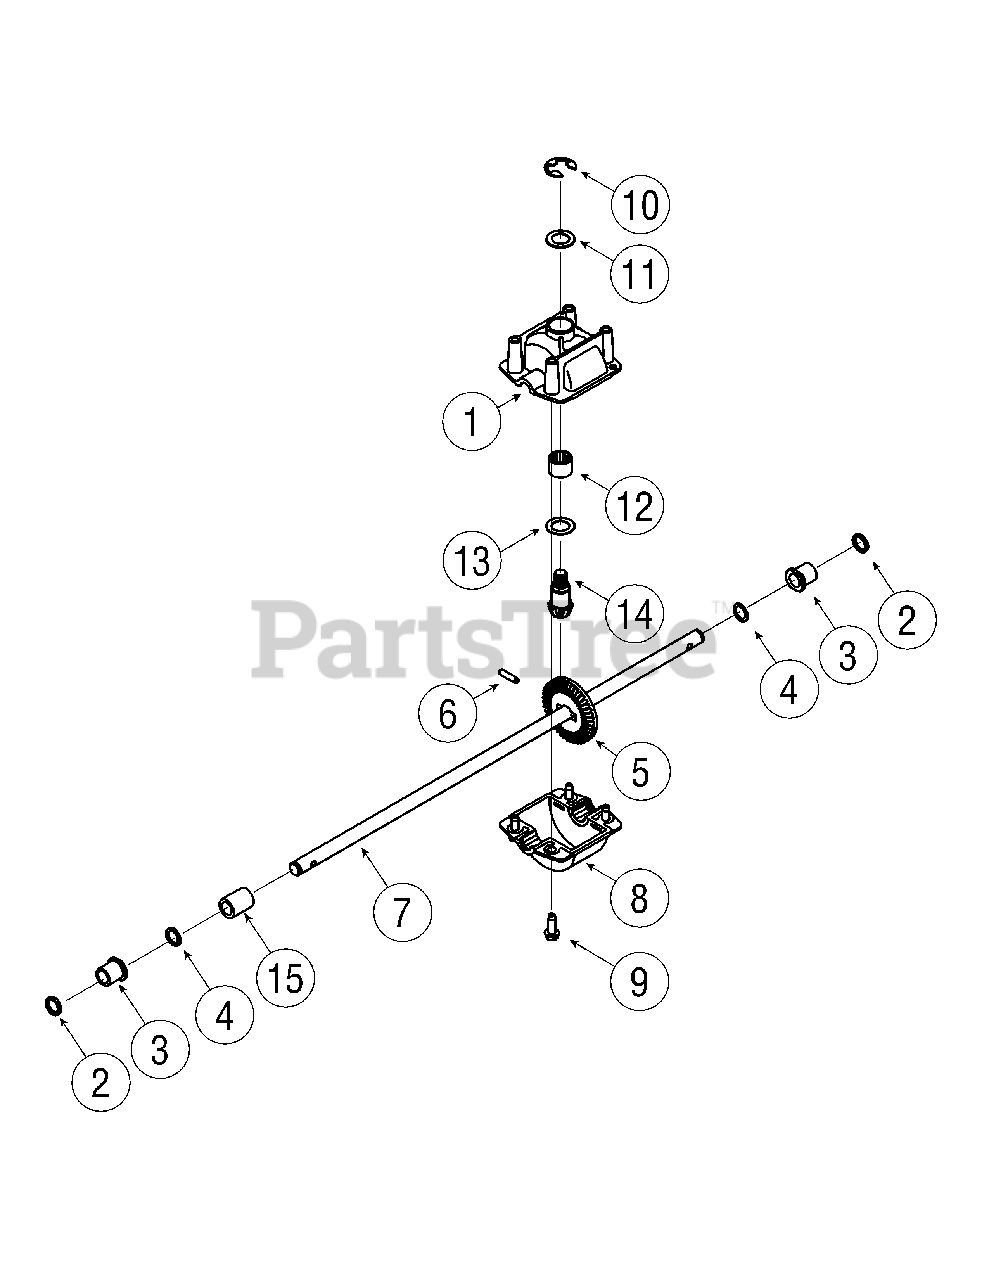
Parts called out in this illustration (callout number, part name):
1	Upper Housing Assembly
2	Oil Seal.500 ID x.687 OD
3	Flange Bearing.503 ID x.689
4	Flat Washer .504 ID x.700 OD x .030
4	Flat Washer .504 ID x.700 OD x .035
4	Flat Washer .504 ID x.700 OD x .040
4	Flat Washer .504 ID x.700 OD x .045
5	Bevel Gear 44T
6	Roll Pin
7	Output Shaft
8	Lower Housing
9	Hex Washer Screw 1/4-20 x.75
11	Flat Washer .625 ID x 1.0 OD x.030
11	Flat Washer .625 ID x 1.0 OD x .040
11	Flat Washer .63 ID x 1.0 OD x .020
11	Flat Washer .632 ID x 1.0 OD x .035
11	Flat Washer .632 ID x 1.0 OD x .025
12	Needle Bearing.625 x.813
13	Flat Washer .625 ID x 1.0 OD x .030
13	Flat Washer .632 ID x 1.0 OD x .035
15	Spacer.505 x.75 x.9765
